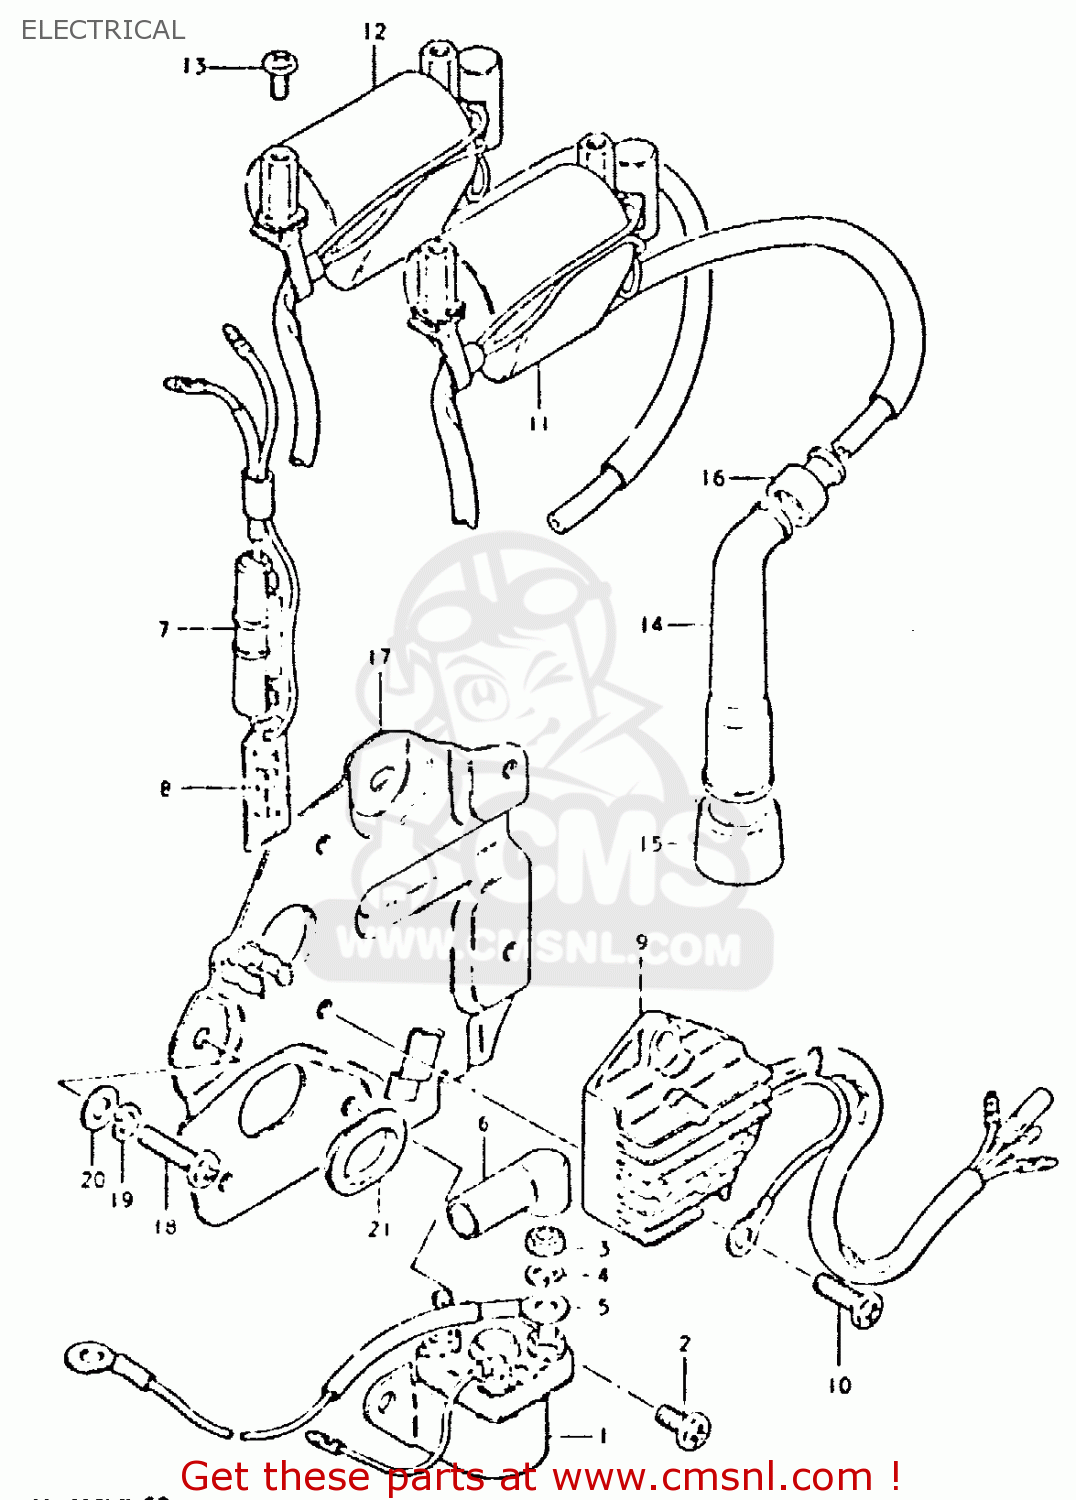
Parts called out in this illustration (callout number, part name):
1	RELAY ASSY,STARTING MOTOR
2	SCREW
3	NUT 6MM
4	LOCK WASHER
5	CORD,BATTERY MINUS
6	CAP,STARTER RELAY
7	BOX ASSEMBLY,FUSE
8	FUSE(15A)
9	RECTIFIER ASSEMBLY
10	SCREW
11	COIL ASSEMBLY,IGNITION
12	COIL ASSEMBLY,IGNITION
13	SCREW
14	CAP ASSY,SPARK PLUG
15	SEAL,SPARK PLUG
16	SEAL,SPARK PLU
17	PLATE,ELECTRIC PARTS H
18	SCREW
19	LOCK WASHER
20	WASHER
21	GROMMET
